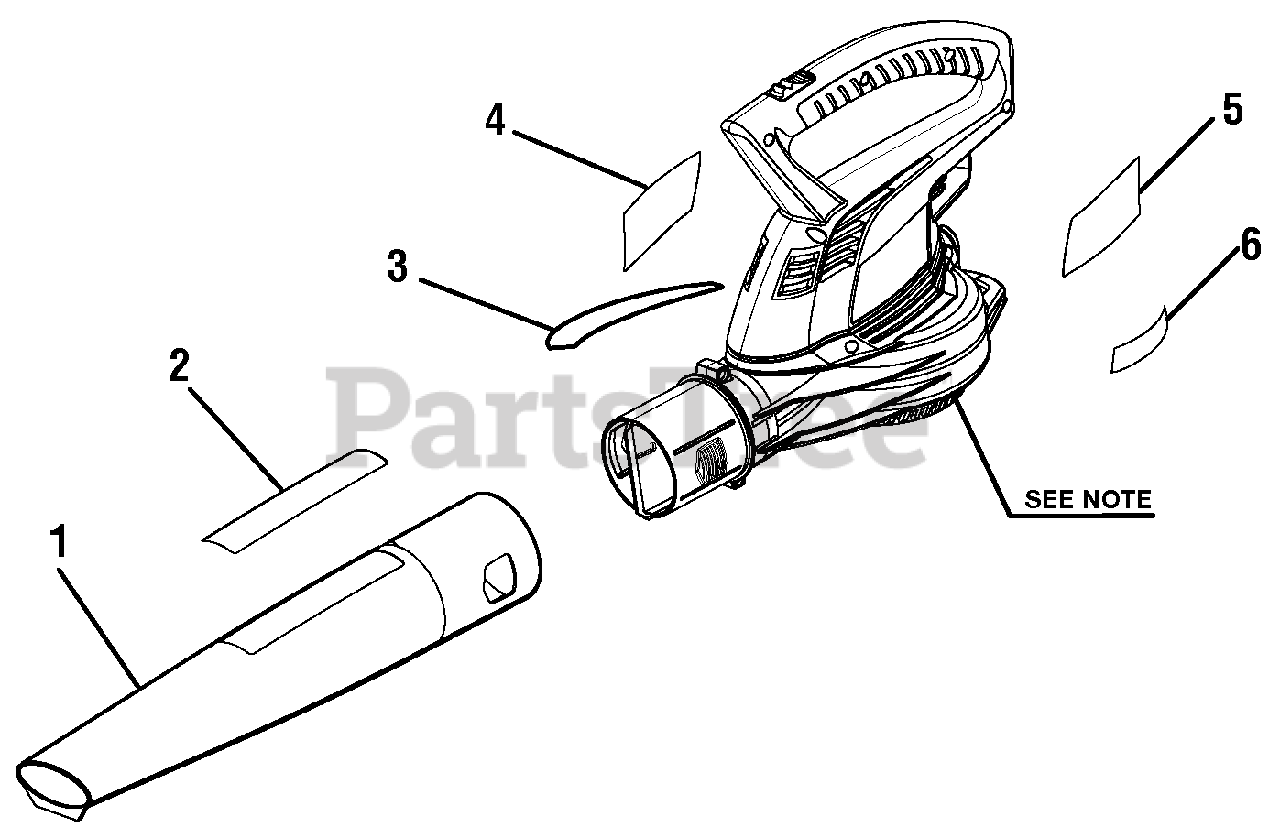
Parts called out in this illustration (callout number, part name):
1	Blower Tube
2	Logo Label (Blower Tube)
3	Warning Icon Label
5	Data Label
6	Warning Label (Spanish)
